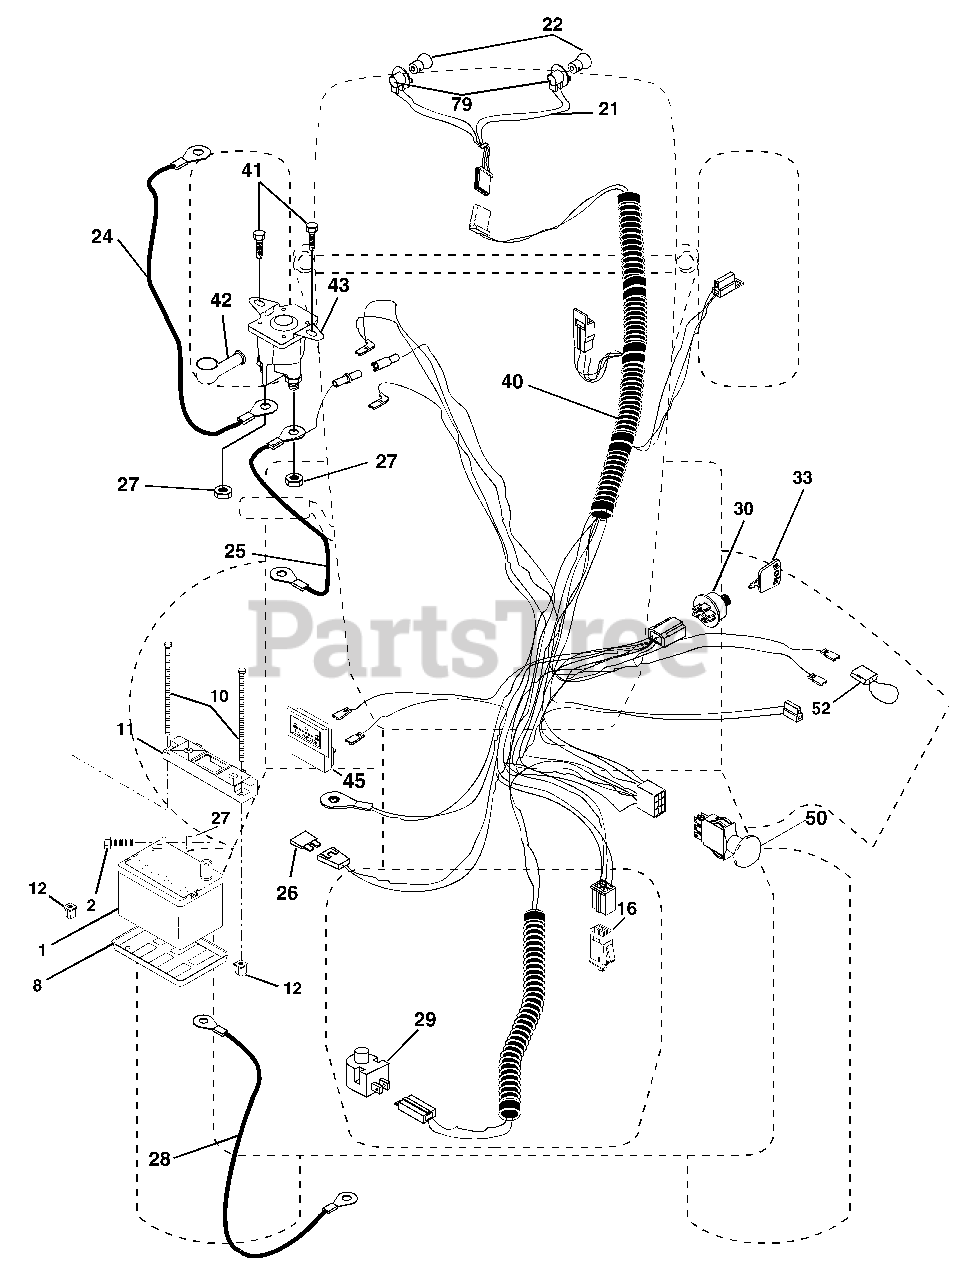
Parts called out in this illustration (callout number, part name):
1	Battery
2	Bolt Hex Head 1/4-20 x 3/4
8	Tray, Battery
10	Bolt 1/4-20 x 7.5 Zinc
11	Hold down Battery Dash Mount
12	Nut Push Nylon 1/4"
16	Switch Interlock
21	Harness Socket Light W/4152J
22	Bulb Light
24	Cable Battery
25	Cable Battery
26	Fuse
27	Nut Keps Hex 1/4-20 Unc
28	Cable, Ground
29	Switch, Plunger
30	Switch, Ign
33	Key, Ignition
40	Harness Ign.
41	Screw Thd Cut 1/4-20 x 1/2
42	Cover, Terminal
43	Solenoid
45	Ammeter
50	Switch, PTO
52	Protection Wire Loop
79	Socket Asm. Bulb
